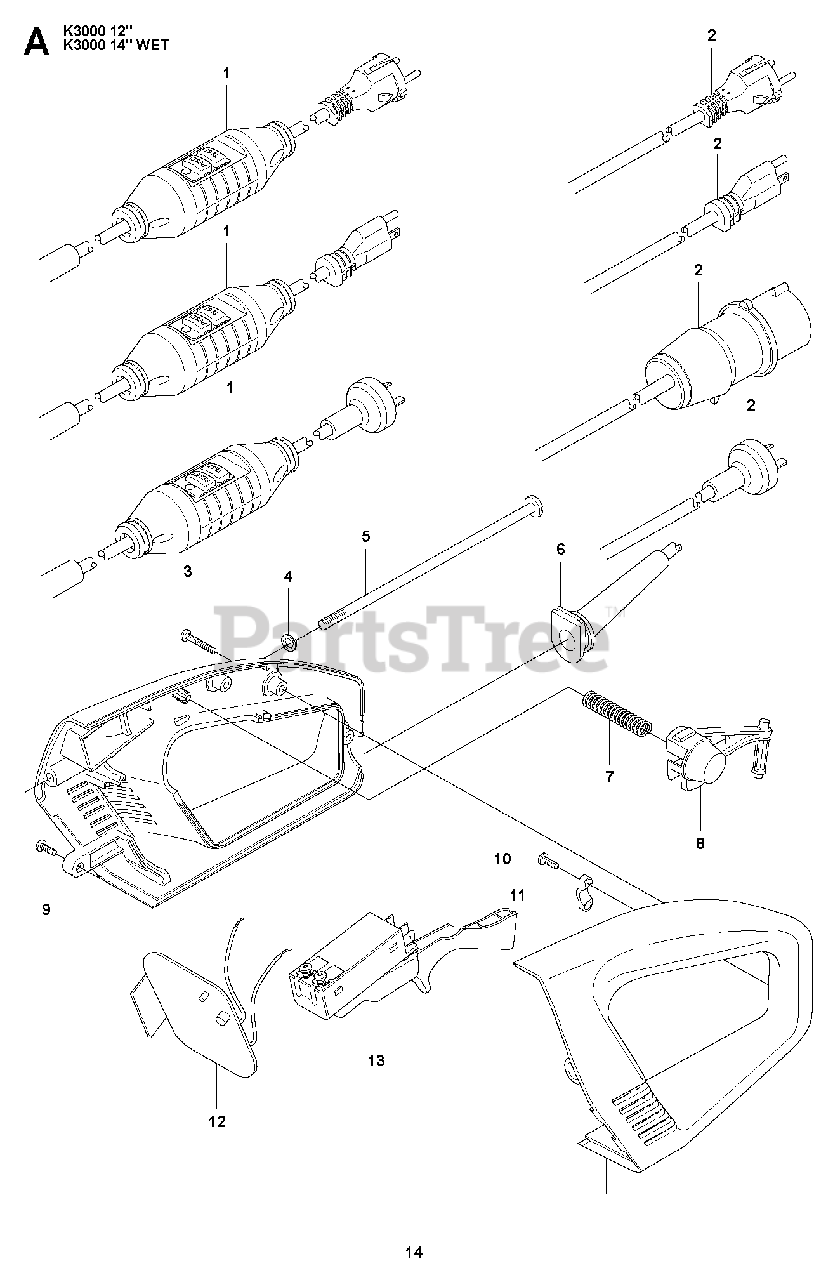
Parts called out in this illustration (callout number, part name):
1	CABLE110V JP, USA
1	CABLE110V AU, Incl. 6
2	CABLE ASSY230V
2	CABLE110V JP, USA
4	SPRING WASHER
6	CABLE SLEEVE230V
7	SPRING
8	LOCKING BUTTON
9	SCREW CRPANM
12	PRINTED CIRCUIT ASSY110V
12	PRINTED CIRCUIT ASSY230V
14	HANDLE ASSY
